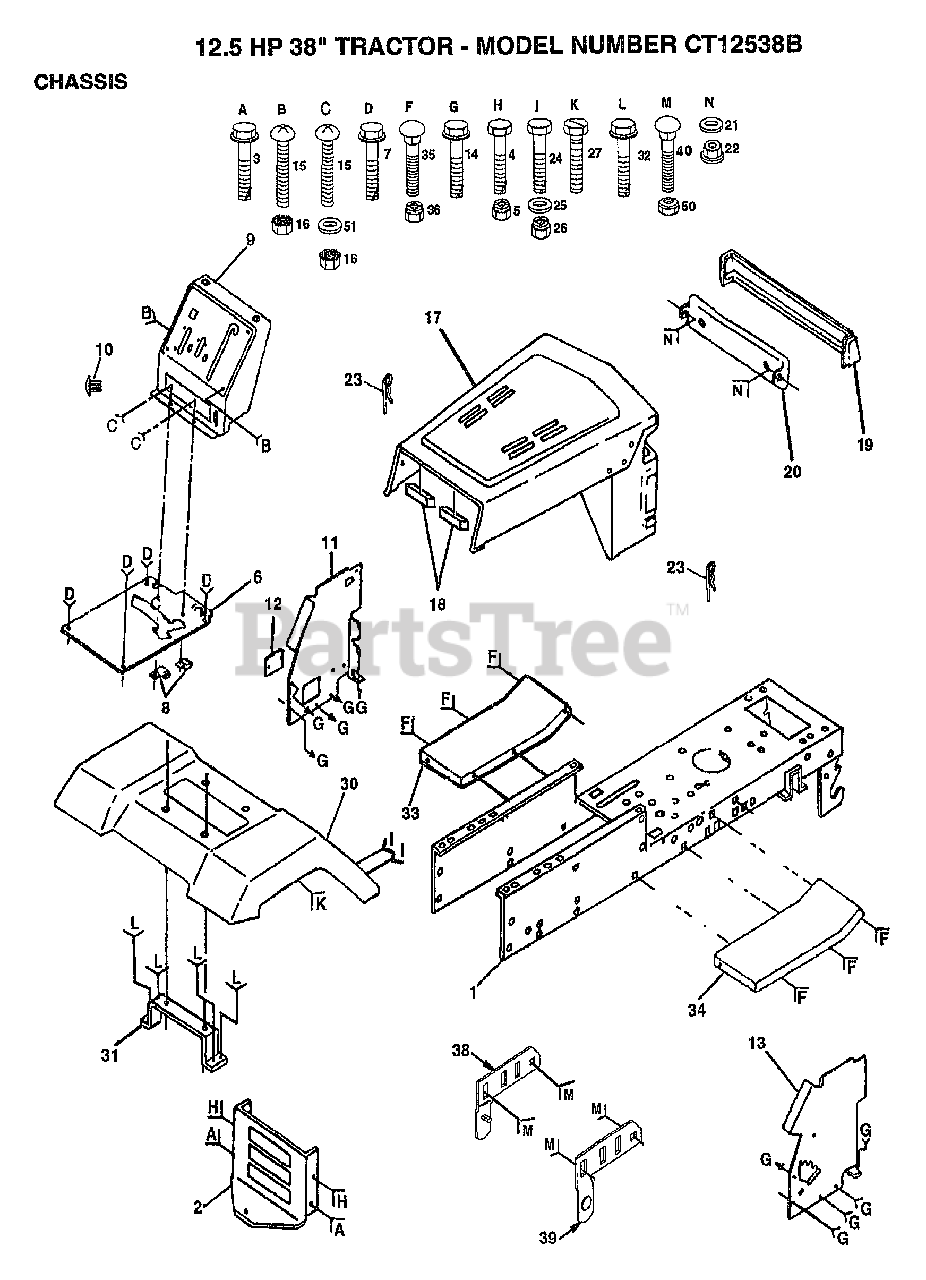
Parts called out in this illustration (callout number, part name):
2	DRAWBAR LT/YT
3	SCREW
7	SCREW LT
8	CLIP T
10	PLUG BUTTON T
11	PANEL DASH LH
12	COVER ACCESS
14	SCREW LT
15	SCREW
17	HOOD/GRILL ASM
19	LENS SERVICE KIT
21	WASHER PM
22	PAL NUT LT
23	SPRING.RETAINER
25	WASHER
27	SCREW LT
30	FENDER
32	SCREW
33	FOOTREST LH
34	FOOTREST RH
35	BOLT
38	BRKT ASM PIVOT LH
39	BRKT ASM PIVOT RH
40	BOLT
50	NUT
51	WASHER
